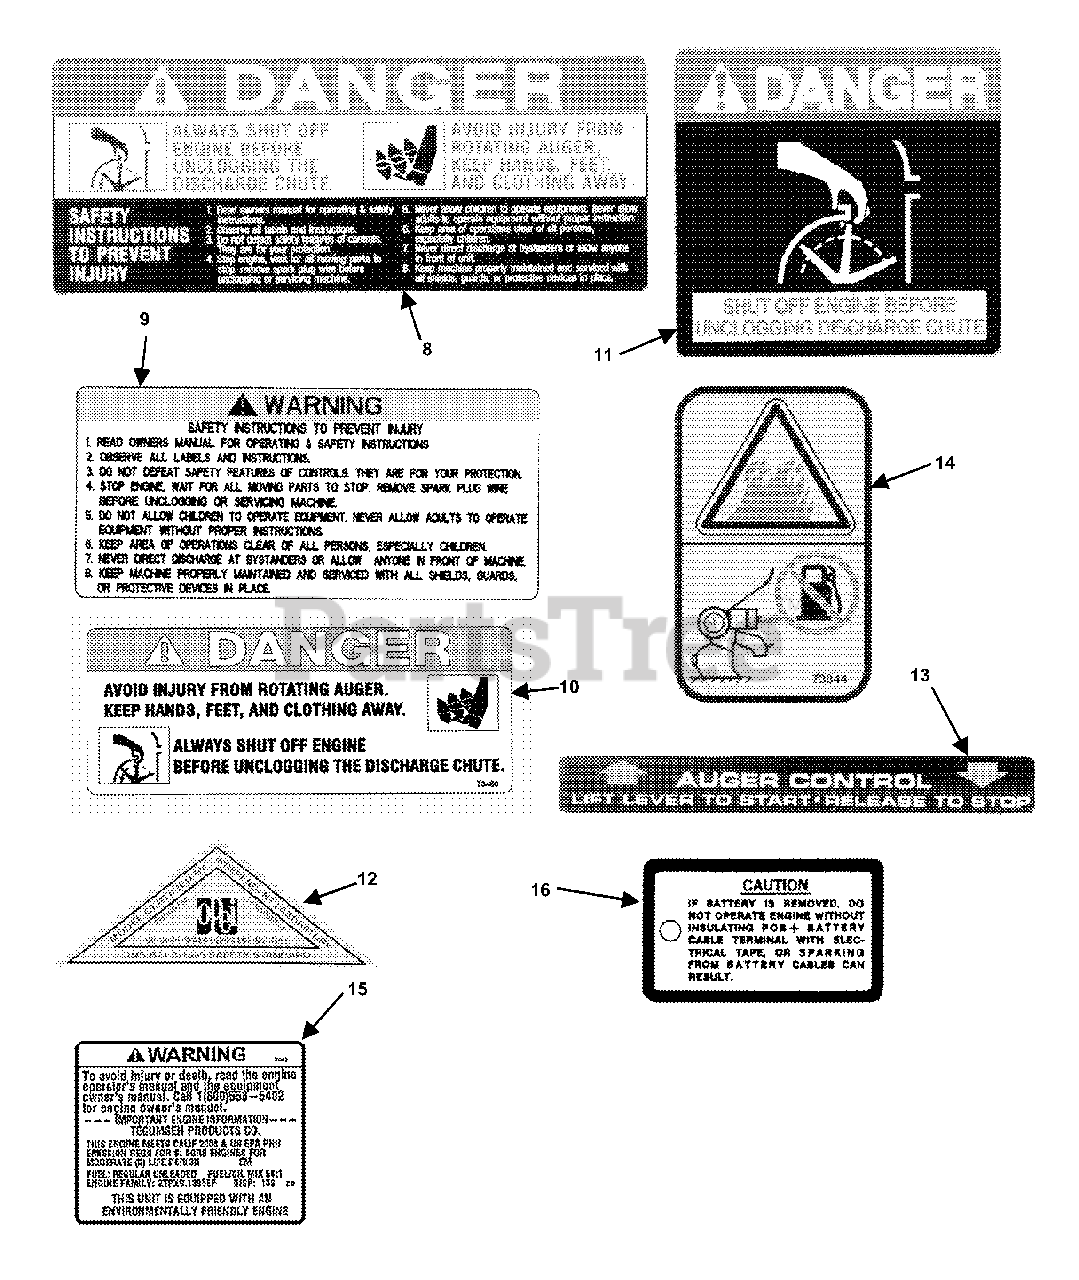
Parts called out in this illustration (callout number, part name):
8	DECAL, Chute Danger
9	DECAL, Warning Safety Instructions
10	DECAL, Danger Chute
11	DECAL, Hand Danger
12	DECAL, OPEI, Snow
13	DECAL, OPC
14	DECAL, Fuel Safety
16	DECAL, Caution Tag
